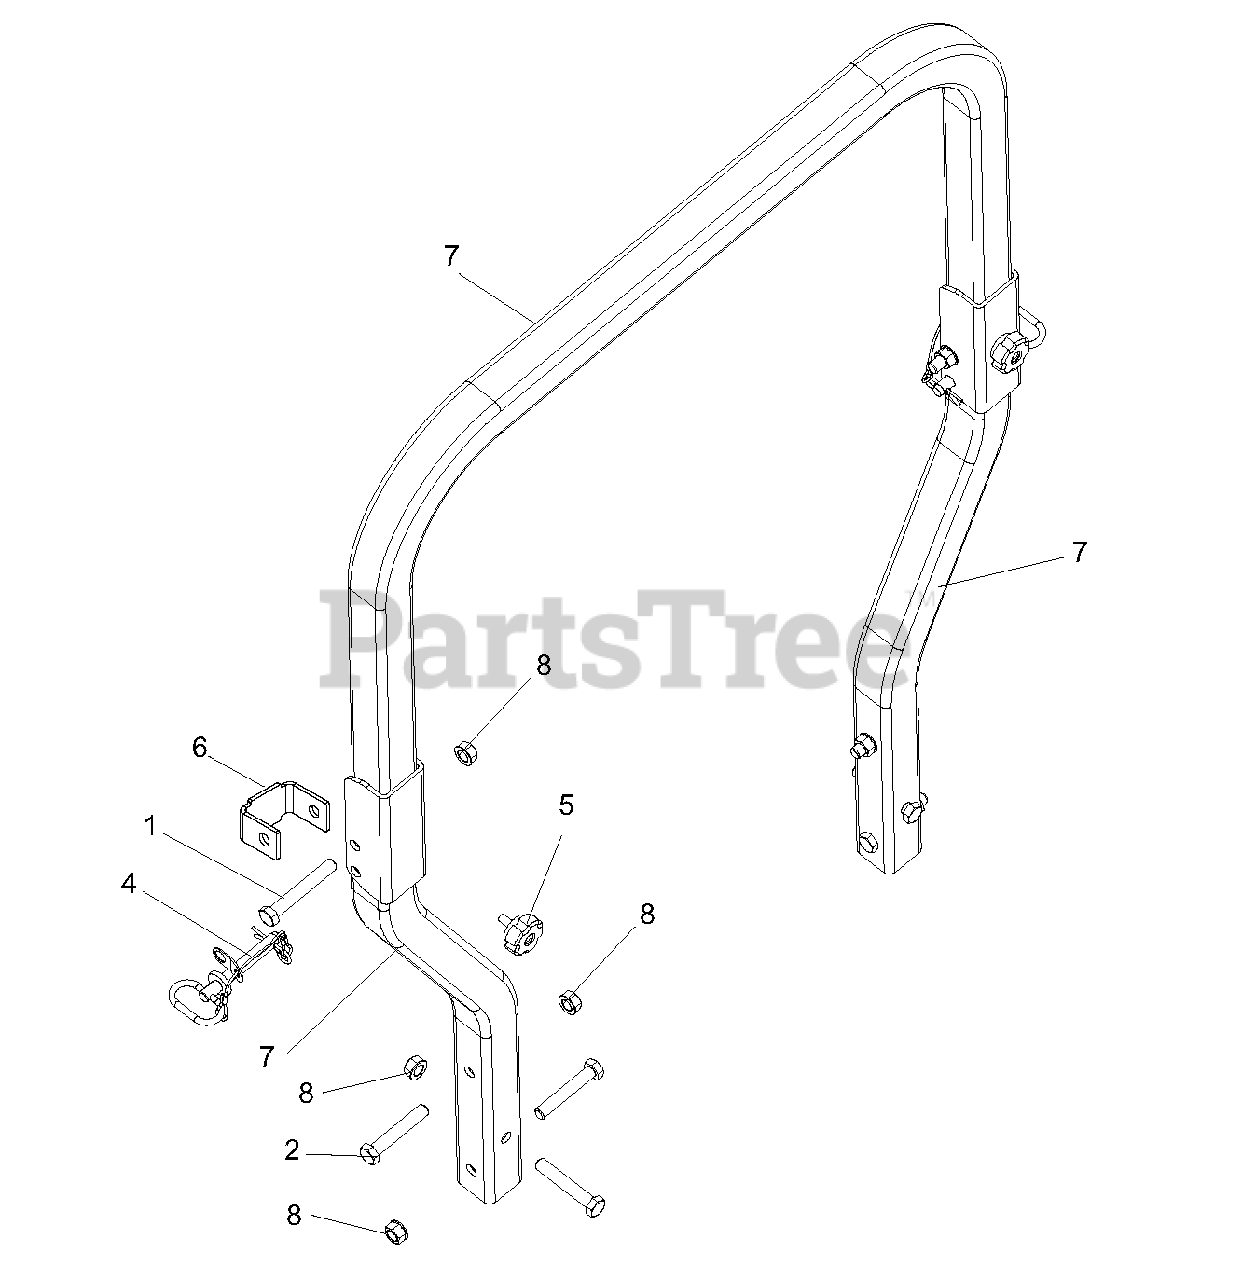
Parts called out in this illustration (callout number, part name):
1	BLT-HEX .50-13X3.50 GR5 YWZC
2	BLT-HEX .50-13X3.00 GR5 YWZC
4	ASSY, ROPS PIN/LANYARD
5	KNOB, ROUND 5/16-18 X .750
6	BRKT, ROPS STOP
7	ROPS, PRO-TURN 400 REPLACEMENT
8	NUT, LK-TOP-FLG .50-13 YWZC
